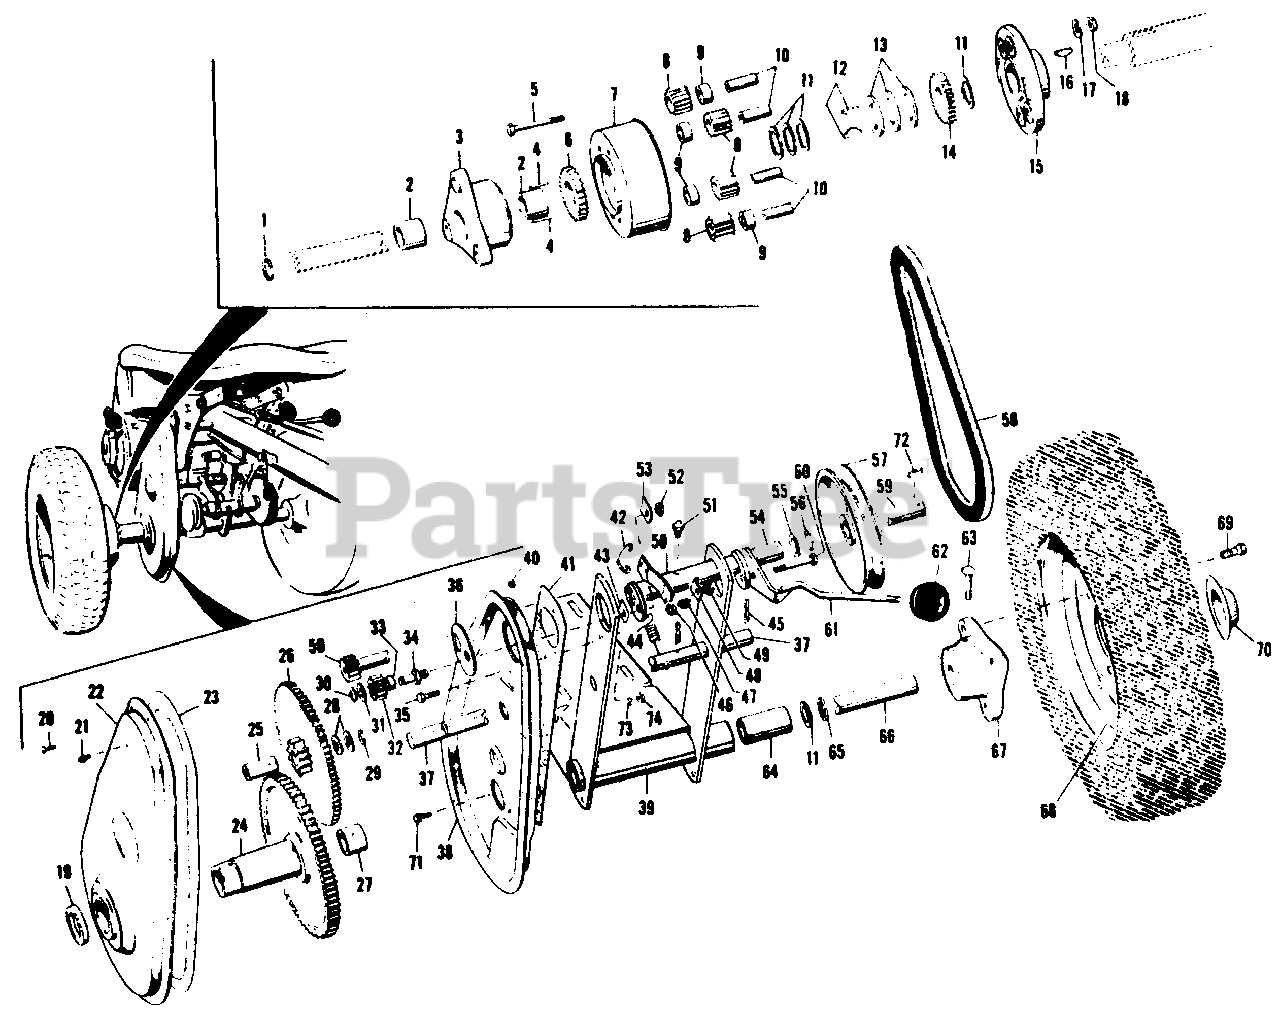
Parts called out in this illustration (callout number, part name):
1	Ring, Retaining
3	Hub, Wheel. R.H.
6	Gear, Differential
7	Cover, Differential
8	Pinion, Differential
9	Spacer, Differential
10	Spindle, Pinion Differential
13	Washer, Axle
14	Gear Differential
15	Carrier, Differential
16	Key, Hi-Pro
22	Cover Assembly
23	Gasket, Case
24	Gear Assembly, Drive
25	Bearing, Intermediate Pinion
26	Gear Assembly, Intermediate (available only as 2 gears assd.)
29	Ring, Retaining
30	Ring, Retaining
31	Washer Reverse Pinion
32	Plnion Assembly, Reverse with Bearing
34	Stud Reverse Pinion
37	Shaft, Intermediate
38	Case Gear
39	Housing, Assembly, Axle
41	Gasket, Bearing Housing
42	Spring, Extension
44	Sring, Reverse Lever
48	Plate, Friction
50	Housing Assembly, Bearing
52	Nut, Hex L.H.
53	Plate, Lock
56	Ring, Retaining
57	Pulley, Transmission
58	Eng. Drive "V" Belt-A33S Super Combine 35" Long
59	Pinion and Pulley Shaft Assembly
61	Lever Assembly, Shaft
64	Bearing, Axle
65	Ring, Retaining
66	Axle, Hear
67	Hub, Wheel, L.H.
68	Wheel, Less Tire and Tube
69	Bolt, Hub
70	Cap, Hub, Rear
